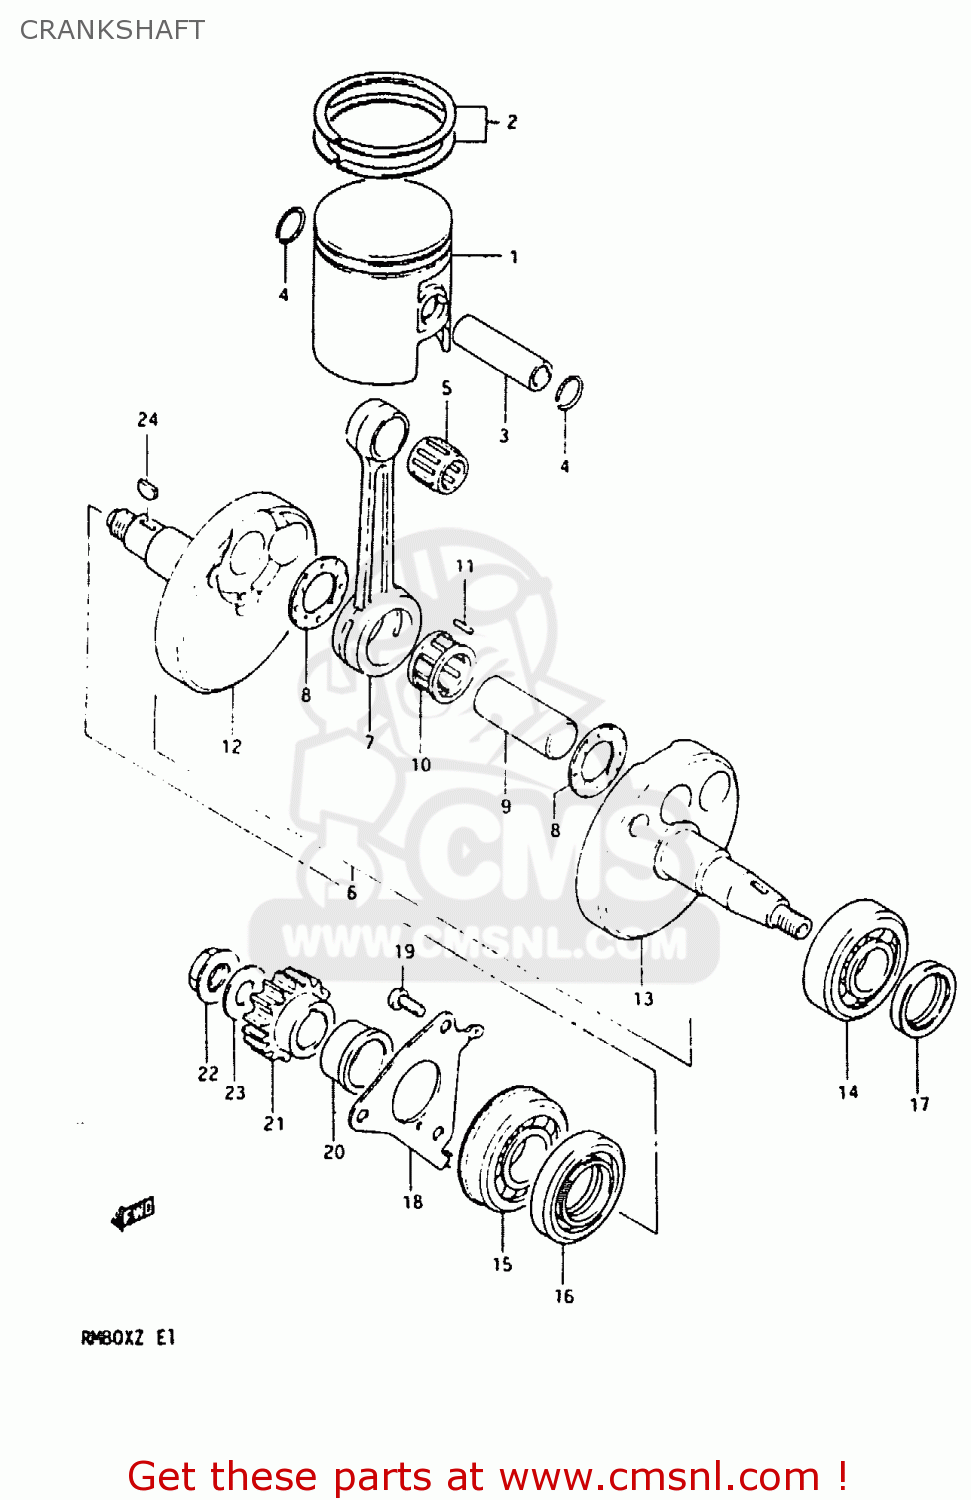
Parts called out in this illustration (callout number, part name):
1	PISTON (STD)
2	RING SET,PISTON
3	PIN,PISTON
4	RING,SNAP
5	BEARING(12X16X16)
6	CRANKSHAFT ASSEMBLY
7	ROD,CONNECTING
8	WASHER
9	PIN,CRANK
10	CAGE
11	ROLLER(3X11)
12	CRANKSHAFT
13	CRANKSHAFT,LEFT
14	BEARING
15	BEARING(20X47X14)
16	SEAL,OIL(26X47X7.3)
17	SEAL,OIL(18X30X8)
18	PLATE
19	SCREW 6X12
20	SPACER,PRIMARY DRIVE GEAR
21	GEAR,PRIMARY DRIVE
22	NUT
23	WASHER
24	KEY
